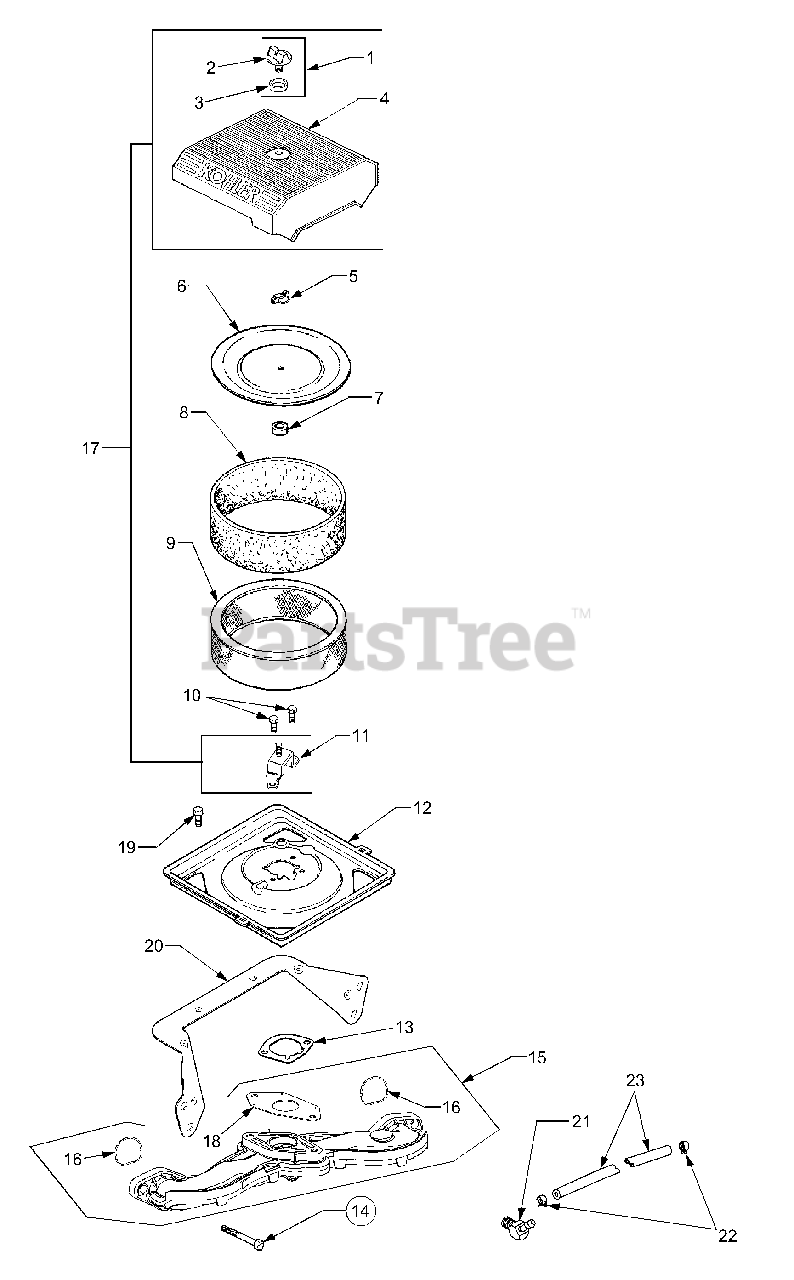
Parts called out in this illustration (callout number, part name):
1	Kit, Knob w/Seal
3	Seal, Air Cleaner Cover Knob
4	Cover, Air Cleaner
6	Cover, Inner Air Cleaner
7	Seal, Inner Air Cleaner
8	Precleaner, Element
9	Element, Air Cleaner
10	Screw, Hex Flange, M6 x 1.0 x16
11	Bracket, Air Cleaner Base
12	Base, Air Cleaner
13	Gasket, Air Cleaner Base
14	Screw, Hex Flange, M6 x 1.0 x 40
15	Manifold, Intake
16	O-Ring, Intake Manifold
17	Kit, Air Cleaner Cover
18	Gasket, Carburetor
19	Screw, Hex Flng, M5 x 0.8 x 10
20	Bracket, Air Cleaner Base
21	Connector, Hose 45°.
22	Clamp, Hose
23	Line, Fuel 17"
